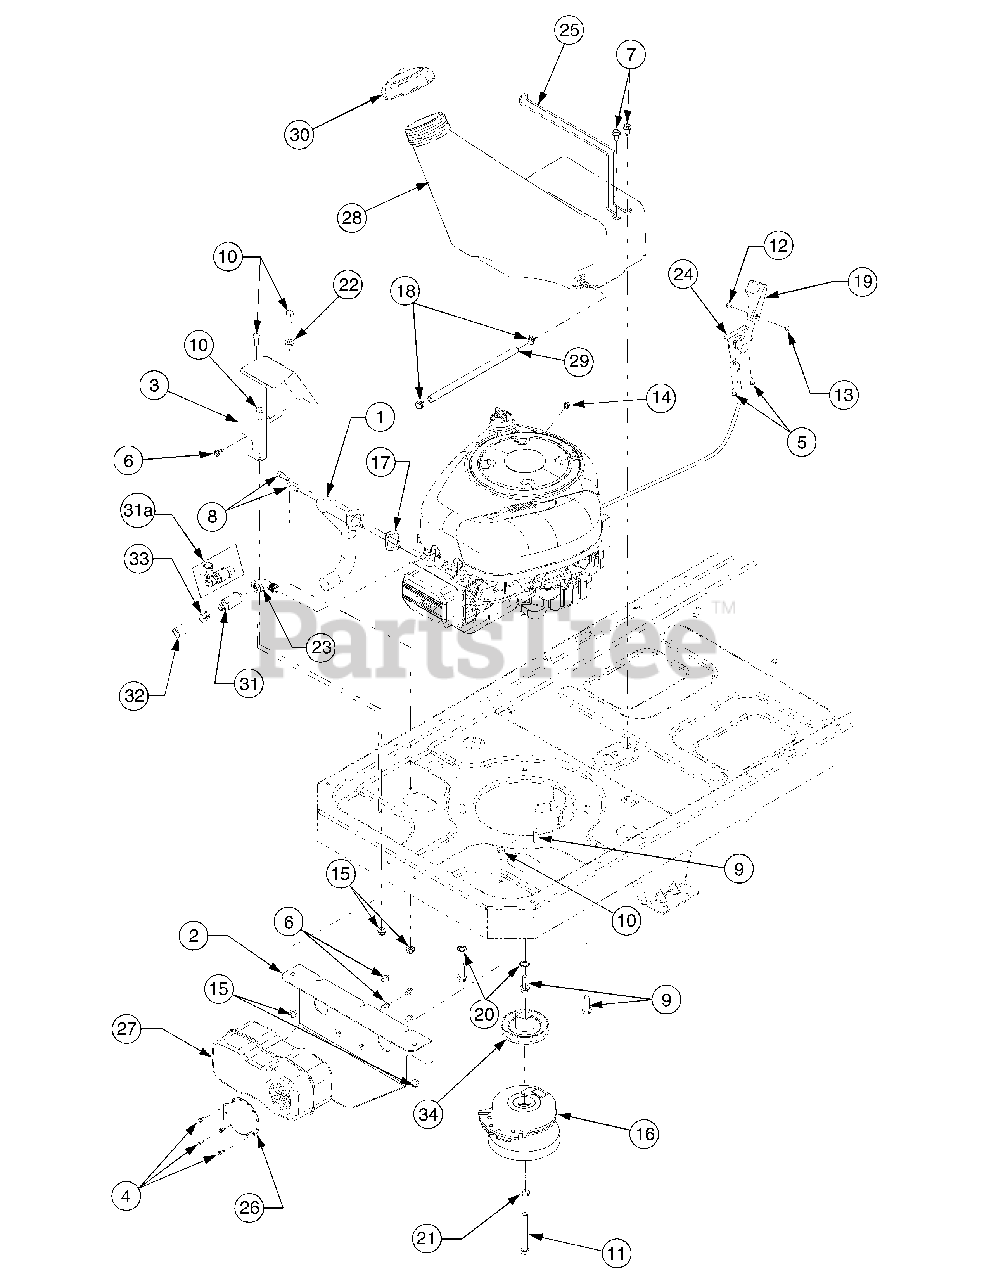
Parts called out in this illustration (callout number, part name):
1	Tube, Exhaust
2	Bracket, Muffler Mounting
3	Shield, Muffler Tube Heat
4	Screw, Hex Wash. Hd. Tapp #8-18 x .5
5	Screw, Hex Wash. Hd. Tapp #12-16 x .5
6	Screw, Hex Wash. Hd. Tapp 1/4-20 x .5
7	Screw, Hex Wash. Hd. Tapp 5/16-12 x .75
8	Screw, Socket Hd. 5/16-18 x .75
9	Screw, Hex Wash. Hd. Tapp 3/8-16 x 1.25
10	Screw, Hex Cap, 5/16-18 x .75 GR5
11	Screw, Hx Cap Lk., 7/16-20 x 3.25 GR5
12	Screw, Truss Hd. Mach. #8-32 x .375
13	Nut, Hex, #8-32
14	Nut, Hex Sems, 1/4-20
15	Nut, Hx Insert Flange Lck, 5/16-18 GrF
16	Clutch Assembly, Electric PTO
17	Gasket, Exhaust (B&S- 272293)
19	Knob, Throttle Control
20	Washer, Ext. Tooth Lock, 3/8
21	Washer, Lock, 7/16
22	Washer, Flat, .344 x .75 x .12
23	Fitting, Elbow
24	Cable, Throttle, 39.0 Lg
25	Wire, Tank Mounting
26	Deflector, Muffler
27	Muffler
28	Tank, Fuel, 3.0 Gal.
29	Hose, Fuel Line 6.5in
30	Cap, Fuel
31	Valve, Oil Drain - Before Mfg. Code C097
32	Hose, Oil Drain Extension
33	Cap, Oil Drain Valve - Before Mfg. Code C097
34	Pulley, Drive
